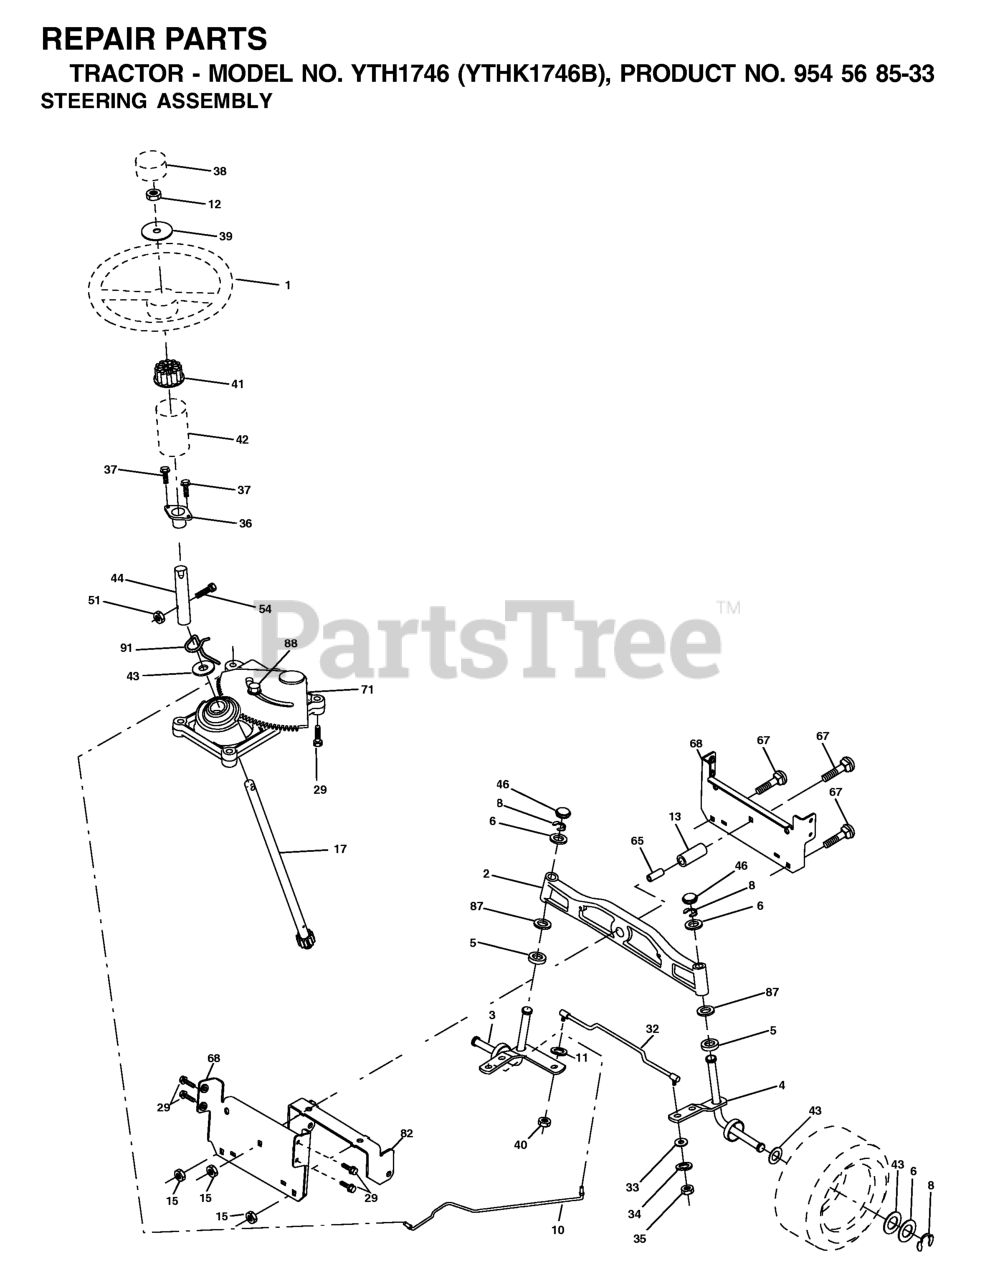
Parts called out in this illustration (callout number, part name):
2	SQUARE KEY
15	WASHER
17	SPRING.BRAKE.HG3000/3500
22	SHIFTER.ASM.GT.TEX.2006
23	KNOB.DUCKHEAD.1/2
26	SPRING.RETURN.CRUISE
29	ROD.BRAKE.0610.PEDAL.CONTROL
35	ROD.BRAKE.PARKING.GT.H
42	PEDAL COVER T
50	IDLER.FLAT.910.OFFSET
51	NUT LOCK FLG 3/8-16 UNC
52	IDLER.V-GROOVE.1.688.OFFSET
64	SHAFT.ASM.PEDAL.BRAKE.
70	RP CONSOLE.ASM.HYDO.HUSQ.
73	BOLT.HEX.FLNG.5/16-18X3.75
74	SCREW.HI-LO.CONSOLE
93	LINK.SHIFT.T/A.0610.TE
114	NUT.71038.31-18.HEX.NYLOCK
116	NUT LOCK HEX FLANGE 5/16-18
125	SCREW
143	Screw 5/16-18 x 1/2 Hex, Self Tapping 5/16-18 x 1/2
159	COTTER PIN
160	RETAINER CLIP
161	SPRING.RETURN.CLUTCH.2006
162	SPACER.TRANSAXLE.18&22
166	NUT.PUSH.625.2006
167	LATCH.BRAKE.SPRING
170	KEEPER.V-IDLER.CENTER.
172	STRAP.TRQ.LH.FS.HG0510
173	STRAP.TORQUE.FS.0610.RH
175	SHAFT.ASM.SHFT.HG0510/
176	ARM.CLEVIS.ROD.SHIFT
178	SPRING.SHIFT.GT2006
183	SPACER AXLE
184	HANDLE.PARKG.BRK.HUSQ X667
186	SPACER.RETAINER
187	WASHER 12/32X2X10GA
188	RP.LINK.CLUTCH.GROUND.DRIVE
189	BELLCRANK.GROUND.DRIVE.TEX.
190	KEEPER.BELLCRANK.DRIVE
195	BRKT.ROD.BRAKE.18/20/2
196	SCREW 3/8-16X1
197	LINK.CLUTCH.ANIT-ROTAT
198	SCREW.7/16-14X7/8.FLAN
200	NUT.CENTERLOCK.5/16-
201	BOLT SHOULDER 5/16-18 UNC
203	WASHER
206	BRKT.MOUNT.LATCH.CRUIS
211	BUSHING.SHAFT.BRAKE.HAND
216	BRACKET.PULLEY.IDLER.W/TEX
220	REFLECTOR.RH.TEX GT
221	RETAINER.SPRING.CLIP.H
276	NUT.PUSH.500.2006
